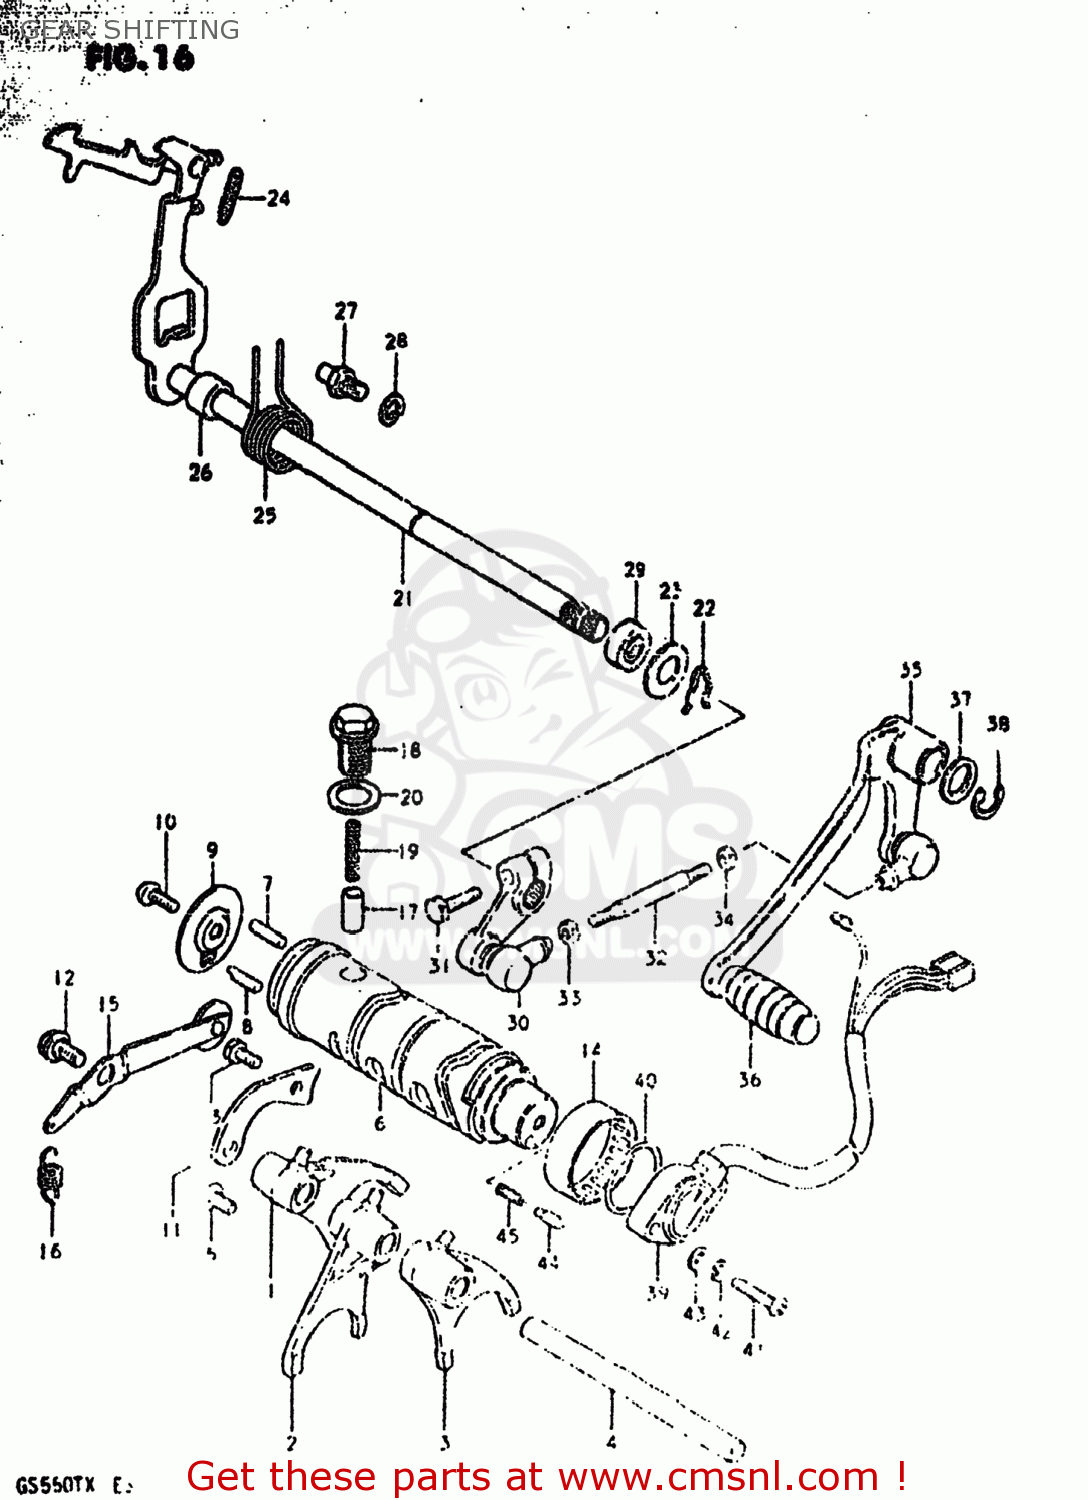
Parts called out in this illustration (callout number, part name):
1	FORK,GEAR SHIFT NO.1
2	FORK,GEAR SHIFT NO.2
3	FORK,GEAR SHIFT NO.2
4	SHAFT,GEAR SHIFT FORK
5	SCREW
6	CAM,GEAR SHIFT
7	PIN(4X18.5)
8	PIN
9	RETAINER,GEAR SHIFT CAM DR PIN
10	SCREW
11	GUIDE,GEAR SHIFTING CABLE
12	BOLT
13	BOLT
14	BEARING(40X47X12)
15	STOPPER,GEAR SHIFT CAM NO.1
16	SPRING
17	STOPPER,GEAR SHIFT CAM NO.2
18	HOLDER,GEAR SHIFT CAM STOP SPR
19	SPRING
20	GASKET(14X19.2X2) (NAS)
21	SHAFT,GEAR SHIFT
22	SPRING,RETAINER
23	WASHER (12.5X27X1.6)
24	SPRING
25	SPRING
26	SPACER(12X20X15.3)
27	STOPPER,GEAR SHIFT CAM
28	WASHER
29	OIL SEAL
30	ARM,GEAR SHIFT LINK
31	BOLT
32	ROD,GEAR SHIFT LINK
33	NUT
34	NUT
35	LEVER ASSEMBLY,GEAR SHIFTING
36	RUBBER,GEAR SHIFT PEDAL
37	WASHER(12.5X20X1)
38	CIRCLIP
39	TERMINAL BASE ASSY,GEAR SHIFT
40	O-RING (D:2.4 ID:26.2)
41	SCREW 5X20
42	LOCK WASHER
43	WASHER
44	PIN(5X15.5)
45	SPRING
